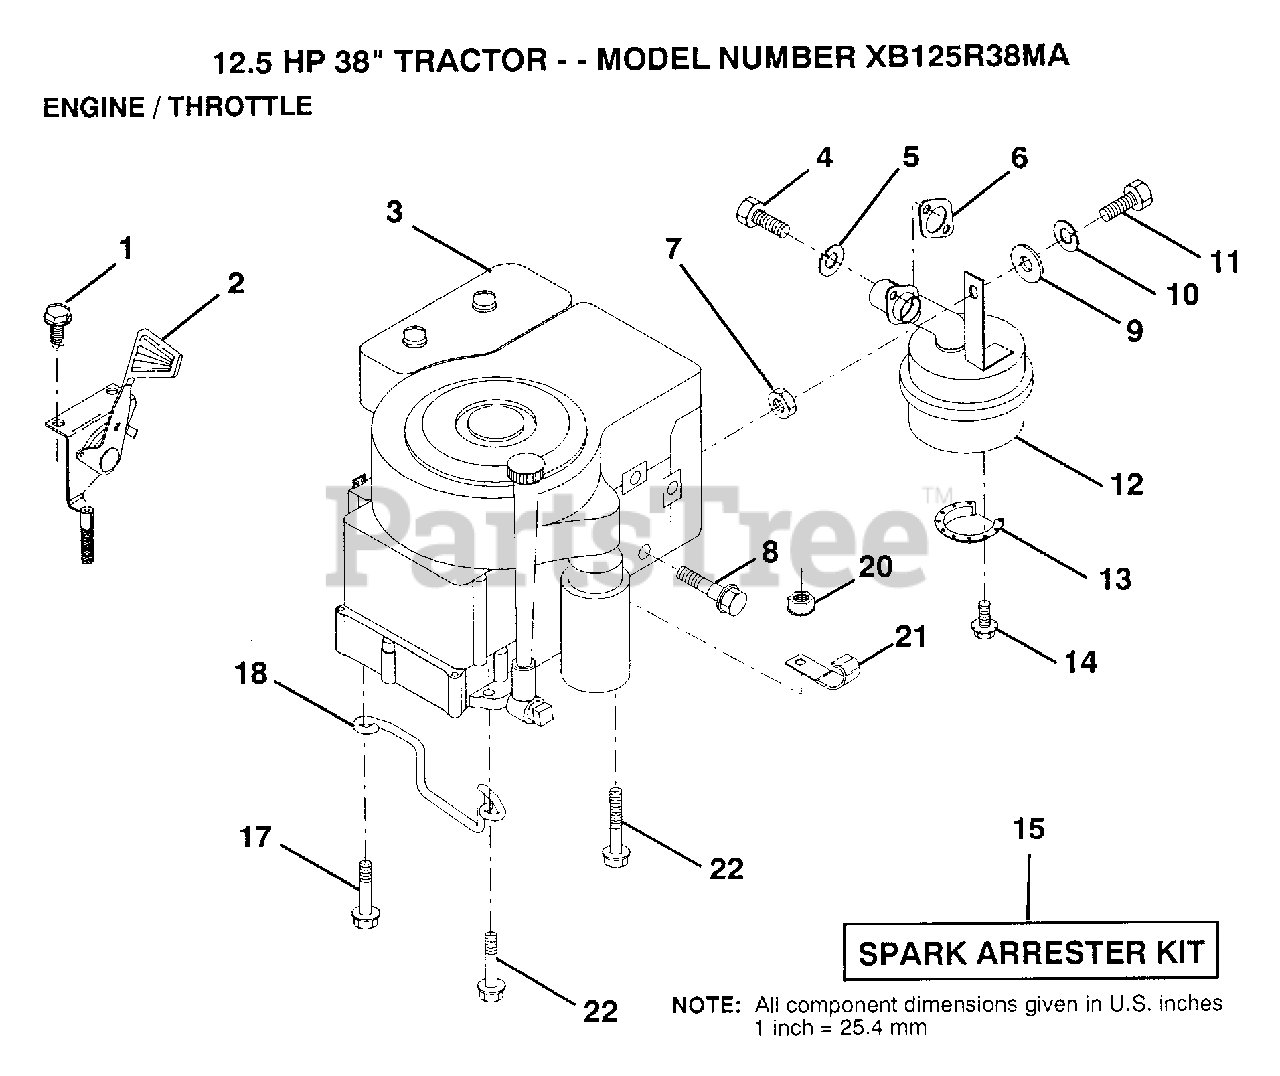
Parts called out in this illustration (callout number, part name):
1	SCREW
2	THROTTLE CONTROL
4	SCREW
5	LOCKWASHER
7	NUT.HEX.5/16-18
8	BOLT T
10	LOCKWASHER
12	MUFFLER
13	DEFLECTOR.222573
17	SCREW LT
18	"KEEPER,DR BELT GR"
20	NUT
21	CLIP T
22	SCREW LT
